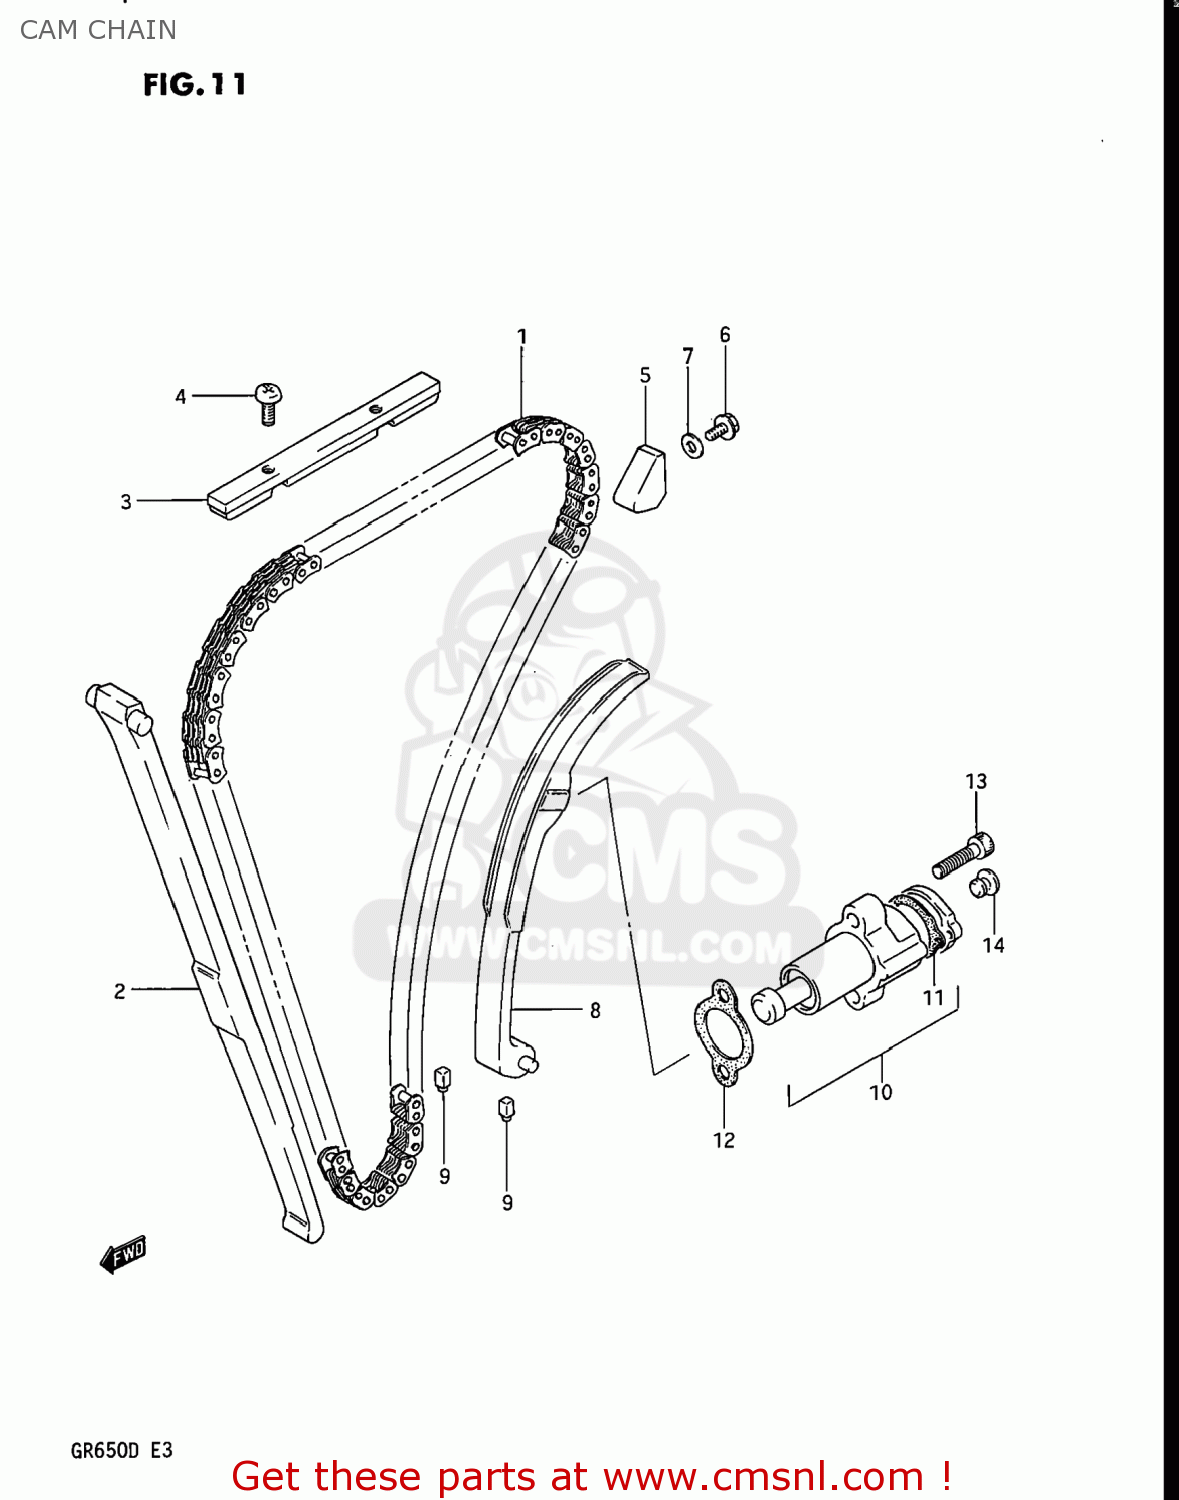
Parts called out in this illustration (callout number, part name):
1	CHAIN,CAMSHAFT DRIVE
2	GUIDE,CAM CHAIN NO.1
3	GUIDE,CAM CHAIN NO.2
4	SCREW
5	GUIDE,CAM CHAIN NO.3
6	BOLT 6X12
7	GASKET (NAS)
8	TENSIONER,CAM CHAIN
9	CUSHION,CAM CHAIN TENSIONER
10	ADJUSTER ASSEMBLY,TENSIONER
11	GASKET,ADJUSTER CAP (MCA)
12	GASKET,TENSIONER ADJUSTER (MCA)
13	BOLT
14	PLUG,ADJUSTER
